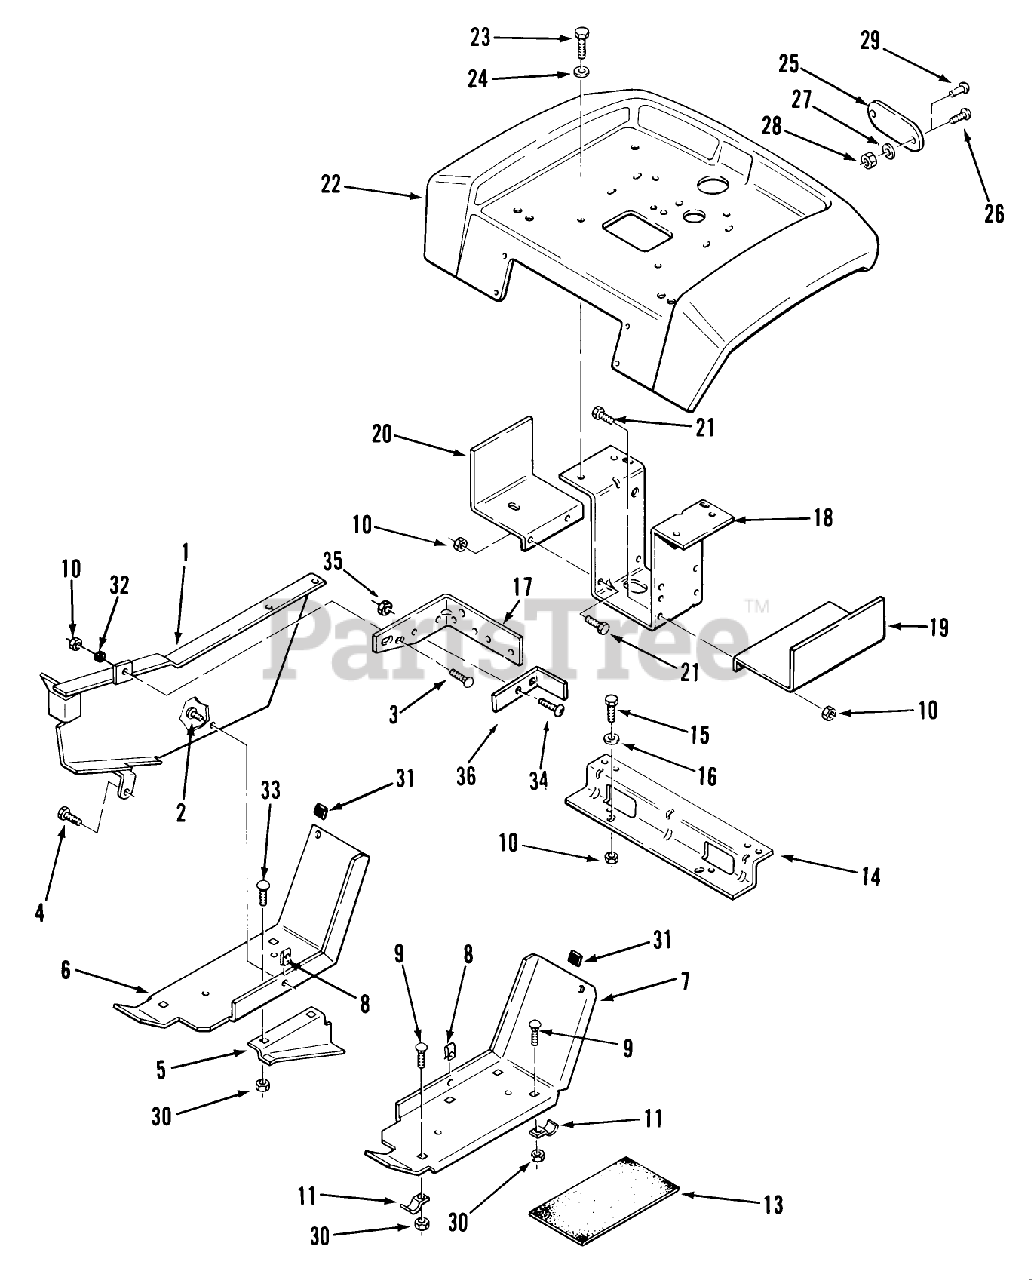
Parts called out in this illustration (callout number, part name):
4	FOOTREST LH *R
6	CARRIAGE BOLT -4
8	BRACKET
9	PAD-FOOTREST
12	WASHER 5/16 SAE
16	NUT
18	SCREW
21	WASHER 5/16 SAE
